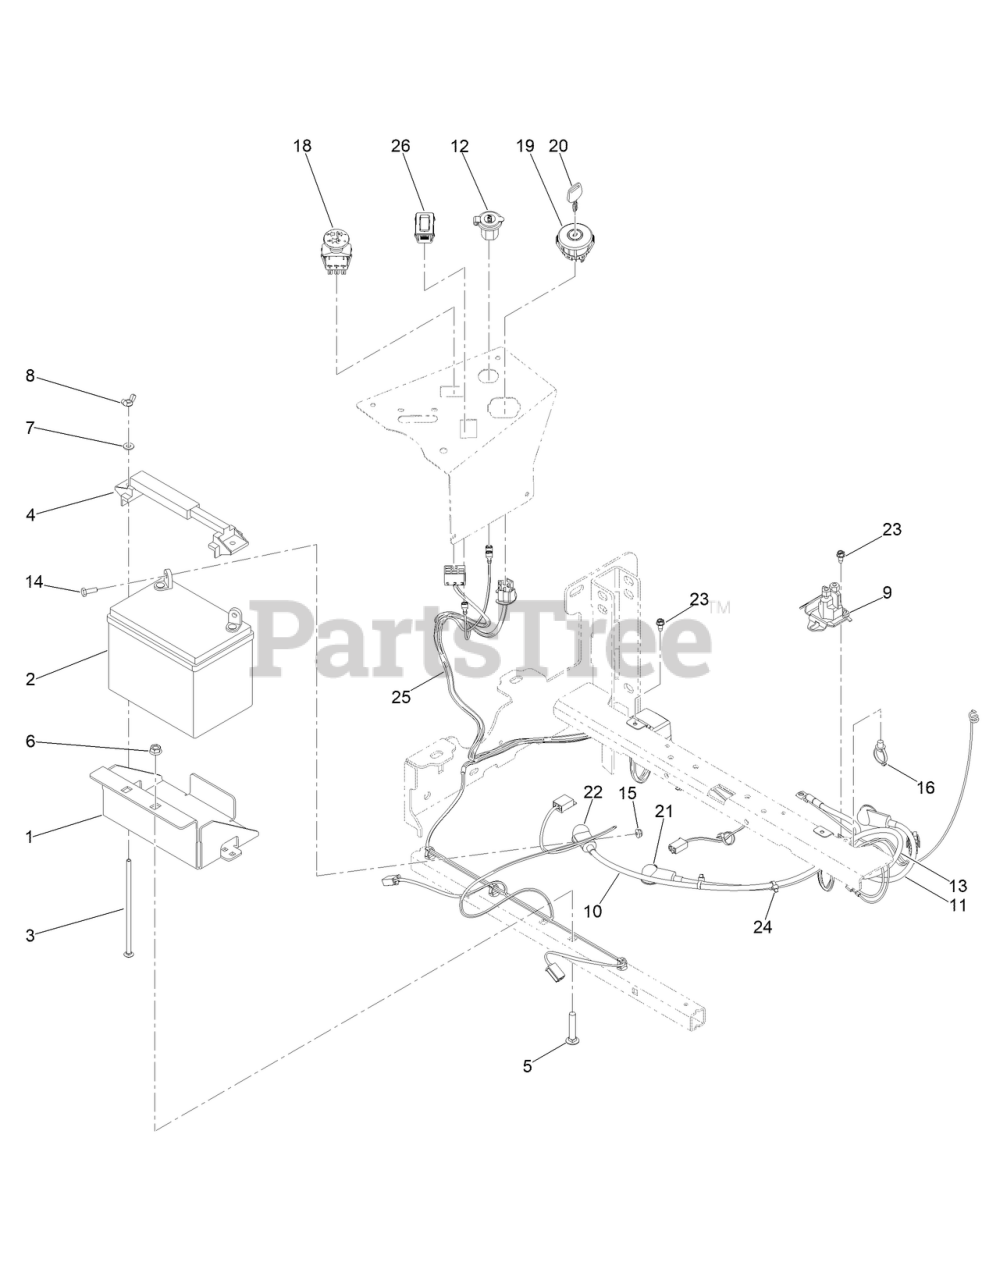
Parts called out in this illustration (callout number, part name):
1	MWR BATTERY BOX
2	12 VOLT START BATTERY 300CCA
3	1/4-20 X 7 CARRIAGE BOLT ZINC
4	BATTERY HOLD DOWN
5	SCREW-CARR
6	3/8-16 HEX FLANGE NUT W/SERR ZINC YELLOW
7	WASHER-FLAT
8	NUT-WING
9	HEAVY DUTY START SOLENOID
10	MWR NEGATIVE CABLE 28
11	MWR START WIRE 12
12	12 VOLT AUXILLIARY PLUG
13	MWR POSITIVE BATTERY CABLE 25IN
14	SCREW-HH
15	NUT-HF
16	CLIP-TIE
18	PTO SWITCH
19	IGNITION SWITCH
20	2023 MWR KEY
21	3.15 LGTH STRAIGHT INSUL TERM COVER RED
22	STRAIGHT INSULATING TERMINAL COVER
23	SCREW-HWH
24	TIE-CABLE
25	HARNESS-WIRE
26	HOUR METER
